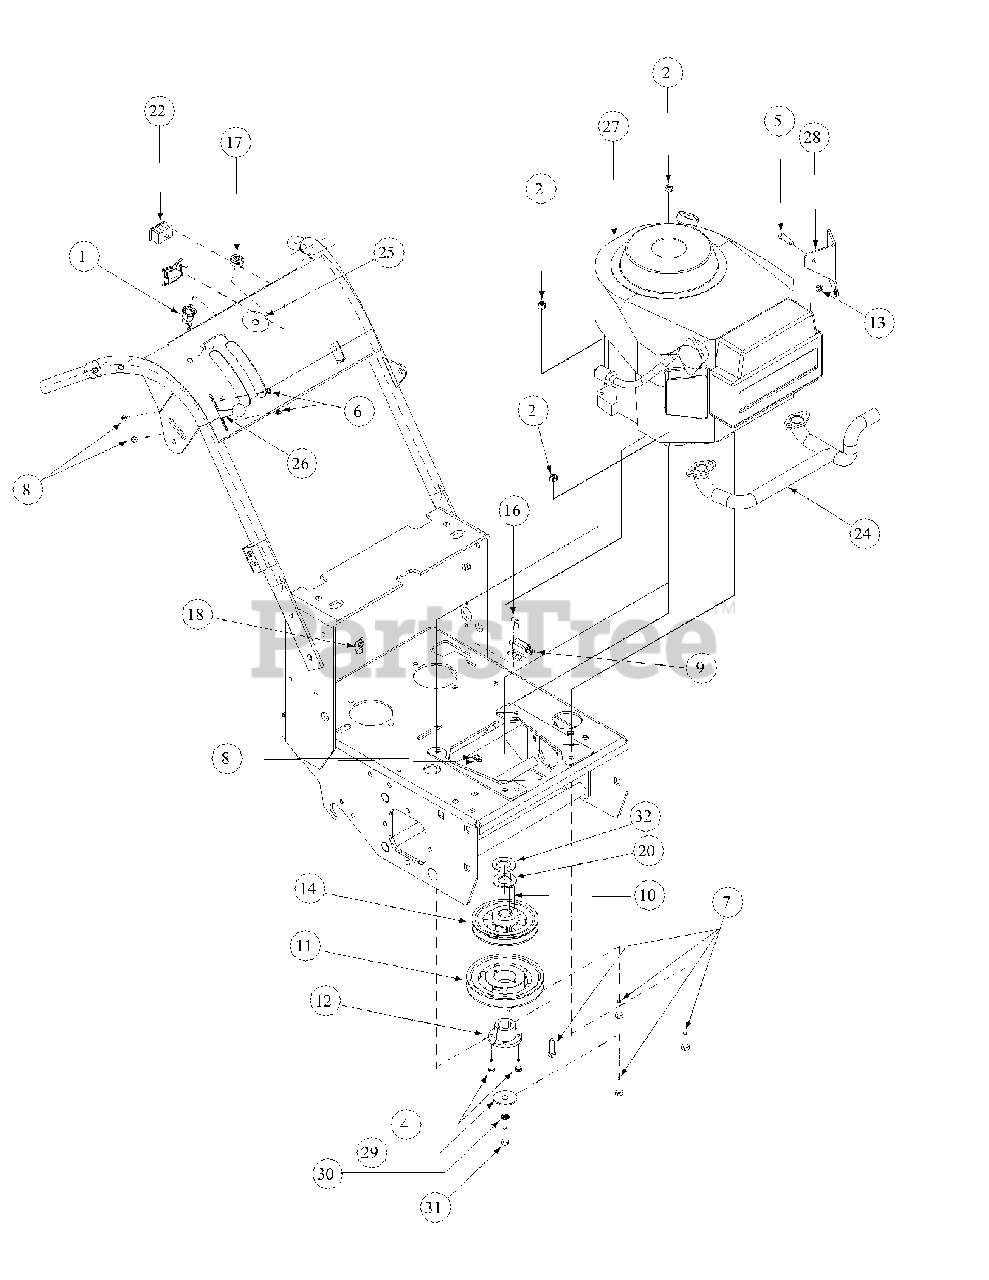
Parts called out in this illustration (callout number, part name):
1	On/Off Ignition Switch
2	Nylock Nut, 5/16-18
4	Hex Cap Screw, 1/4-20, .75
5	Hex Cap Screw, 5/16-18 x 3/4
6	Slotted Hex Washer Screw, 10-32 x 1/2
7	Hex Cap Screw, 5/16-18 x 2
8	Lock Nut, Nylon Insert, #10-32
9	Delta Switch, N.C.
10	Key Stock, 1/4 x 1/4 x 2.75
11	Deck Pulley
13	Hex Nut, Center Lock, 5/16-18
14	Cast Pulley with 1" Bore
16	Phil. He. Mach. Screw #10-32 x 5/8
17	Nut w/Cap, 5/8-32 Ignition
18	Support Clamp, 3/8 OD
19	Harness Wire
20	Flat Washer
22	Hour Meter
23	Harness Hourmeter
24	Kawasaki Manifold
25	Decal, Pull Start Overlay
26	Throttle Control w/Detent, 57.25
27	Kawasaki Engine, 15HP
28	Muffler Kawasaki Bracket
29	Clutch Washer
30	Lock Washer, 7/16
31	Capscrew, 7/16-20 x 1-1/4
32	Spacer Pulley Engine
